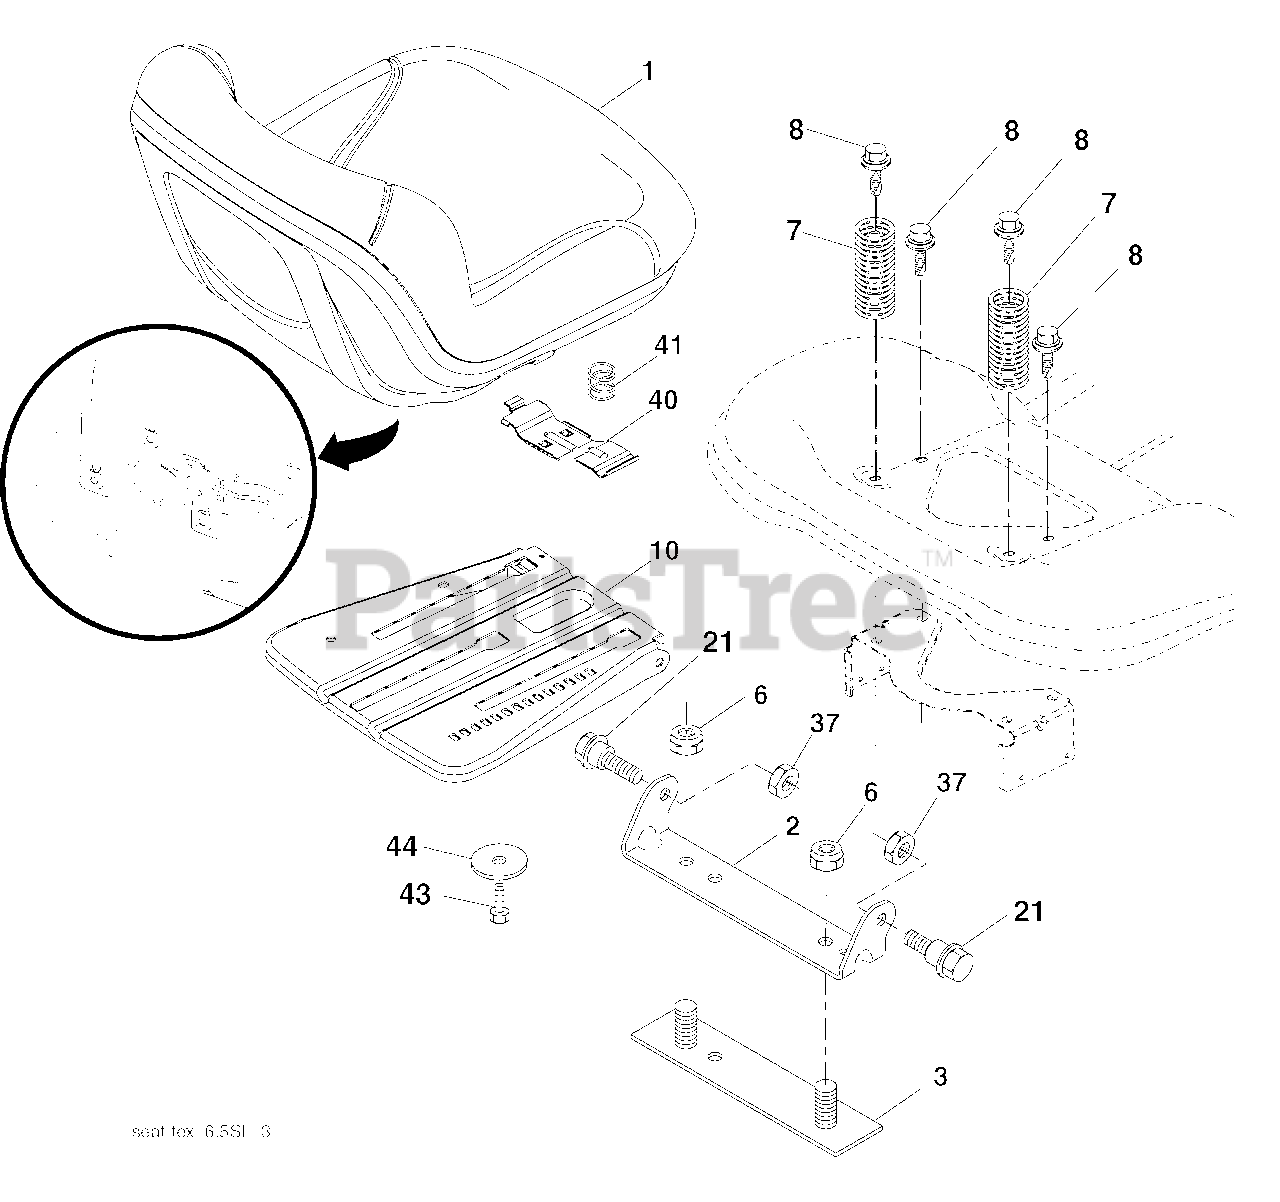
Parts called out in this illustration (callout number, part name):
1	Seat
2	Bracket Pivot Fender
3	Strap, Asm. Fender
6	Nut, Lock w/Ins. 3/8-16 unc
7	Spring, Seat Cprsn.
8	Bolt 5/16-18 unc x 3/4 w/Sems.
10	Pan, Seat
21	Bolt, Shoulder 5/16-18
37	Nut, Lock 5/16-18 unc
40	Handle Slide Seat
41	Spring Latch Seat
43	Bolt Fin. Hex 3/8-16 unc x 3/4
44	Washer 13/32 x 2-3/8 x 12 Ga.
